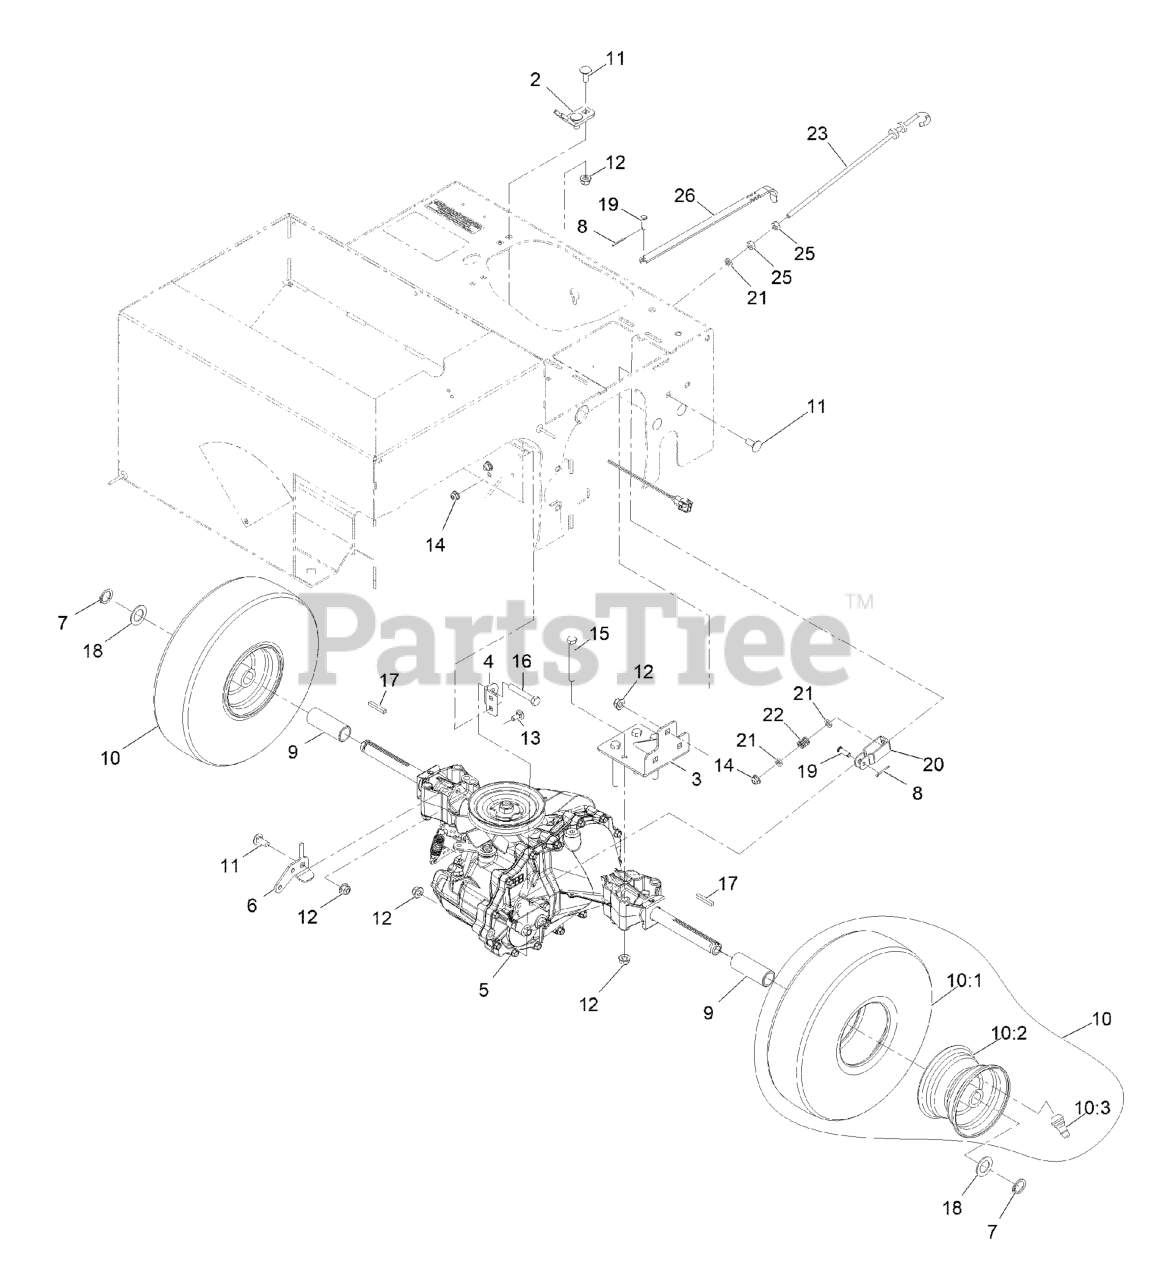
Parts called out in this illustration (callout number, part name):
2	BRACKET-CABLE
3	BRACKET-AXLE
4	BRACKET-TRANSAXLE, TORQUE
5	TRANSAXLE ASM
6	BRACKET-TRANSAXLE
7	RING-RETAINING
8	PIN-COTTER
10	WHEEL ASM
10:2	WHEEL-RIM
10:3	VALVE
11	SCREW-CARR
12	NUT-HF, NI
13	SCREW-CARR
15	SCREW-HH
16	SCREW-HH
17	KEY-SQUARE
19	PIN-CLEVIS
21	SPACER-PLATE, PIVOT
22	SPRING-COMPRESSION
23	ROD-BRAKE
25	NUT-HEX
26	LEVER-BYPASS
